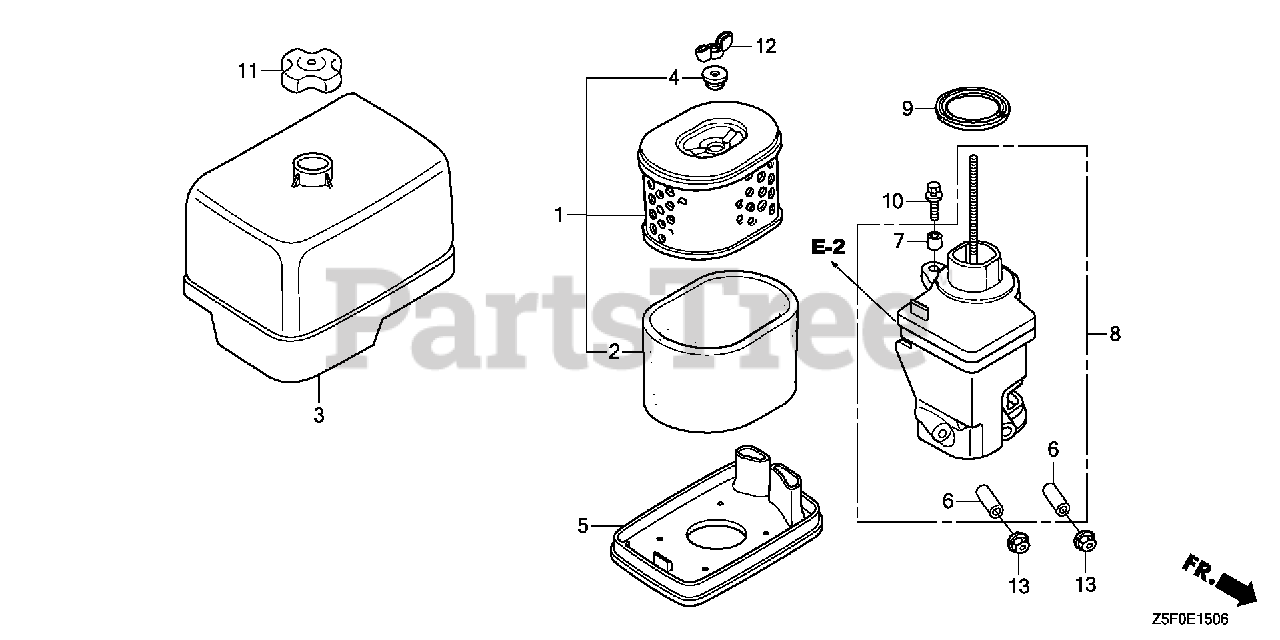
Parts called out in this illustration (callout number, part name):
1	ELEMENT, AIR CLEANER (DUAL)
2	FILTER (OUTER)
3	COVER, AIR CLEANER HOUSING
4	GROMMET, AIR CLEANER
5	NOSE, MUFFLER
6	COLLAR, AIR CLEANER
7	COLLAR B, AIR CLEANER
8	ELBOW, AIR CLEANER
9	GASKET, AIR CLEANER HOUSING
10	BOLT-WASHER (6X22)
11	NUT, AIR CLEANER COVER
12	NUT, TOOL BOX SETTING
13	NUT, FLANGE (6MM)
